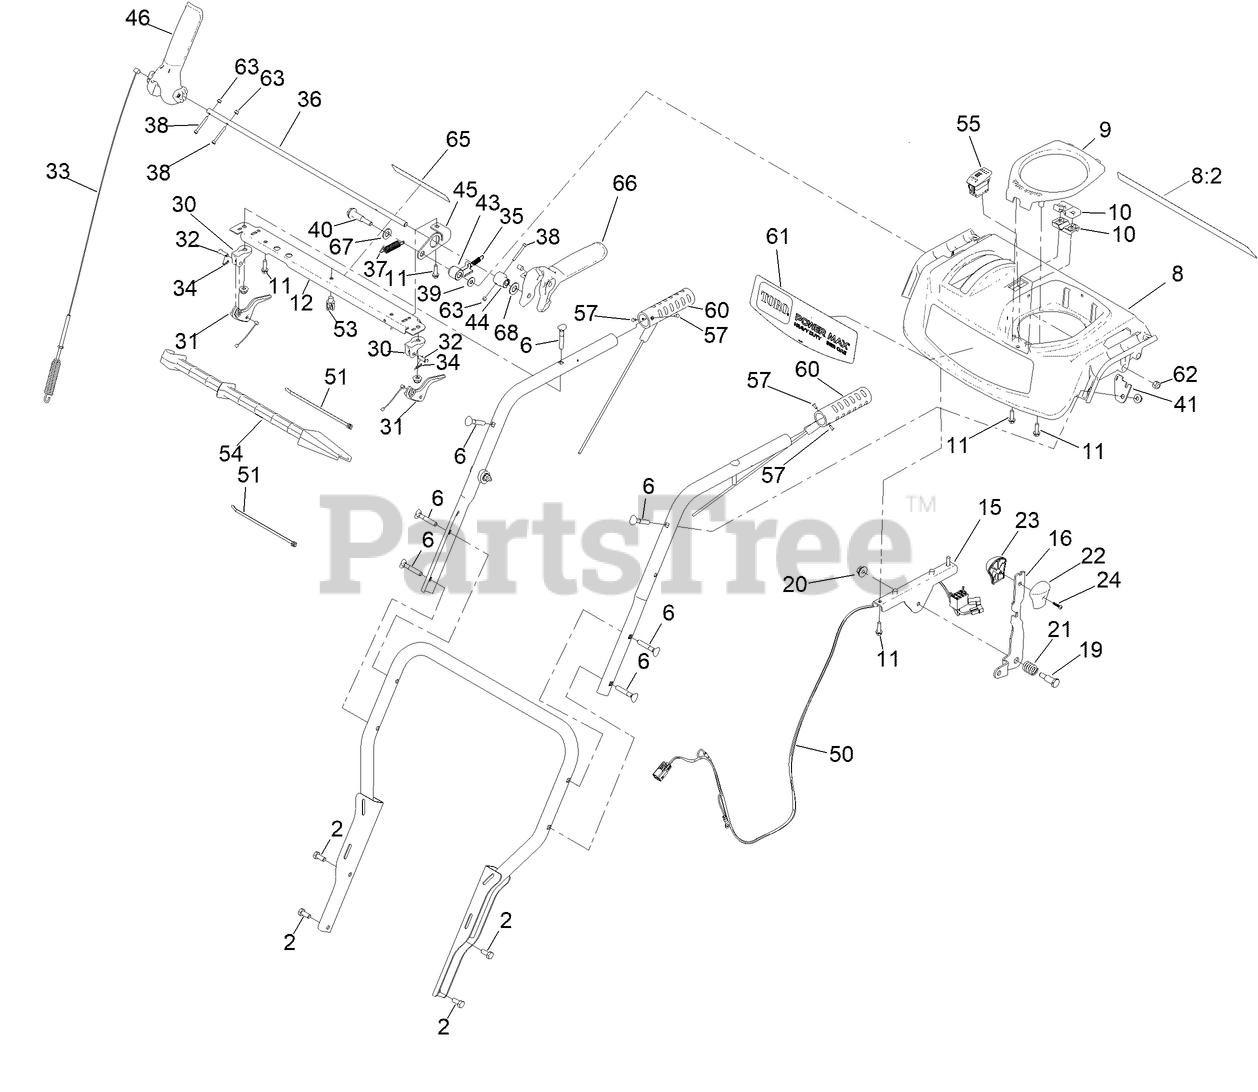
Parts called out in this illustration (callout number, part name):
2	SCREW-HH
6	SCREW-HANDLE
8	PANEL-CONTROL, ASSEMBLY
8:2	DECAL-SAFETY
9	COVER-QUICKSTICK
10	SUPPORT-ROD
11	SCREW-PLASTITE, HWH
12	BRACE-CONSOLE
15	BRACKET-SHIFT
16	SELECTOR-SPEED
19	SCREW-SHOULDER, HH
20	NUT-HF
21	SPRING-COMPRESSION
22	KNOB-SHIFT, LH
23	KNOB-SHIFT, RH
24	SCREW-PPH
30	MOUNT-LEVER, CLUTCH
31	LEVER-CLUTCH
32	PIN-CLEVIS
33	CABLE-AUGER
34	PIN-HAIR
35	SPRING-LOCKOUT, HANDLE
36	ROD-LOCKOUT
37	SPRING-RETURN, LEVER
38	SCREW-HSH,SPL
39	WASHER-FLAT
40	SCREW-SHOULDER
41	PLATE-SPRING
43	LATCH, LOCKOUT
44	CAM-LOCKOUT
45	LINK-LOCKOUT
46	LEVER-CONTROL
50	HARNESS-WIRE, LED AND HAND WARMERS
51	TIE-CABLE
53	CLIP-TIE
54	STICK-CLEANOUT
55	SWITCH-ROCKER, ON-NONE-OFF (HEATER)
57	RIVET-POP
60	RED HEATED GRIP
61	DECAL-CONSOLE
62	NUT-HEX
63	NUT-LOCK ROHS
65	DECAL-HYDRO
66	LEVER-CONTROL
67	WASHER-FLAT
68	WASHER-FLAT
